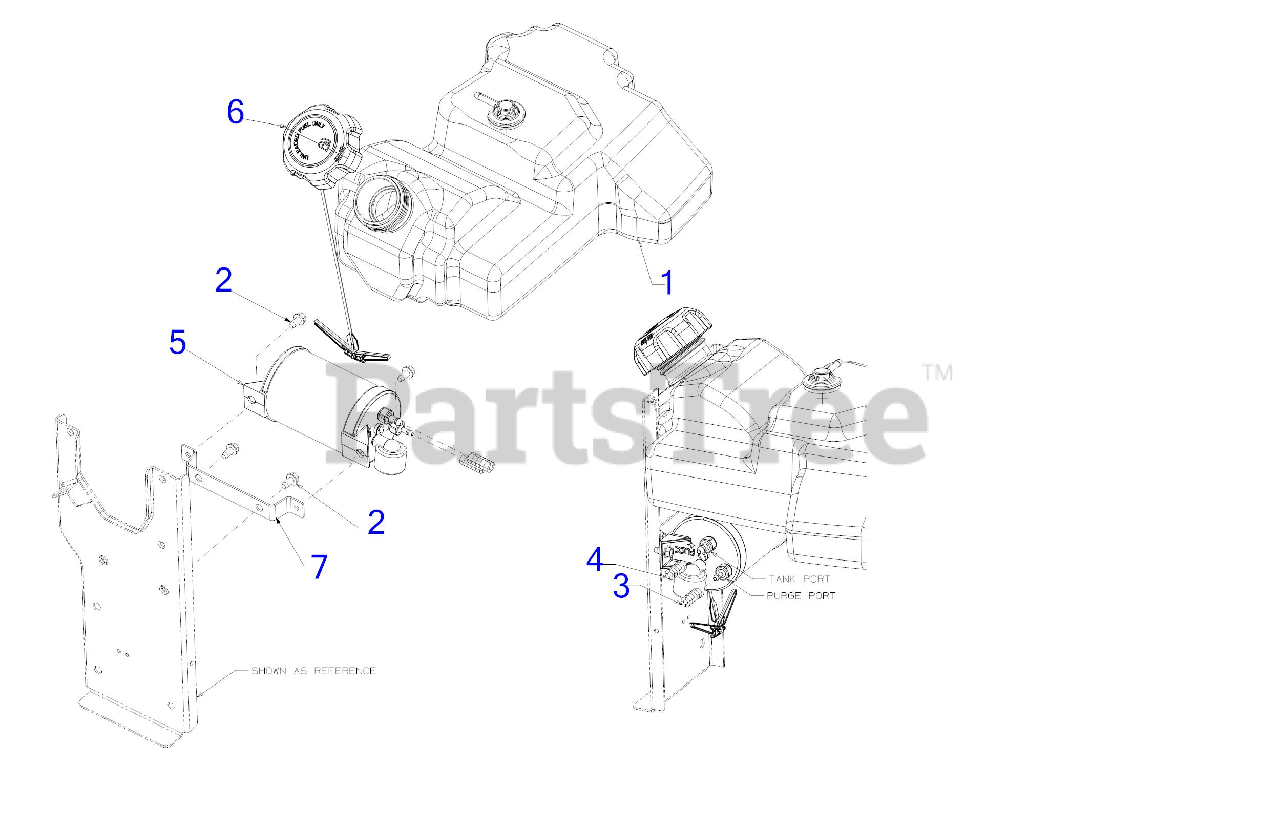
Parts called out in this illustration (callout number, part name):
1	FUEL TANK ASSEMBLY
2	SCREW 1/4-20 X.500
3	FUEL HOSE LO PERMEATION 3/16 WHITE
4	FUEL HOSE LO PERMEATION 7/32 YELLOW
5	CARBON CANISTER
6	FUEL CAP W/TETHER
